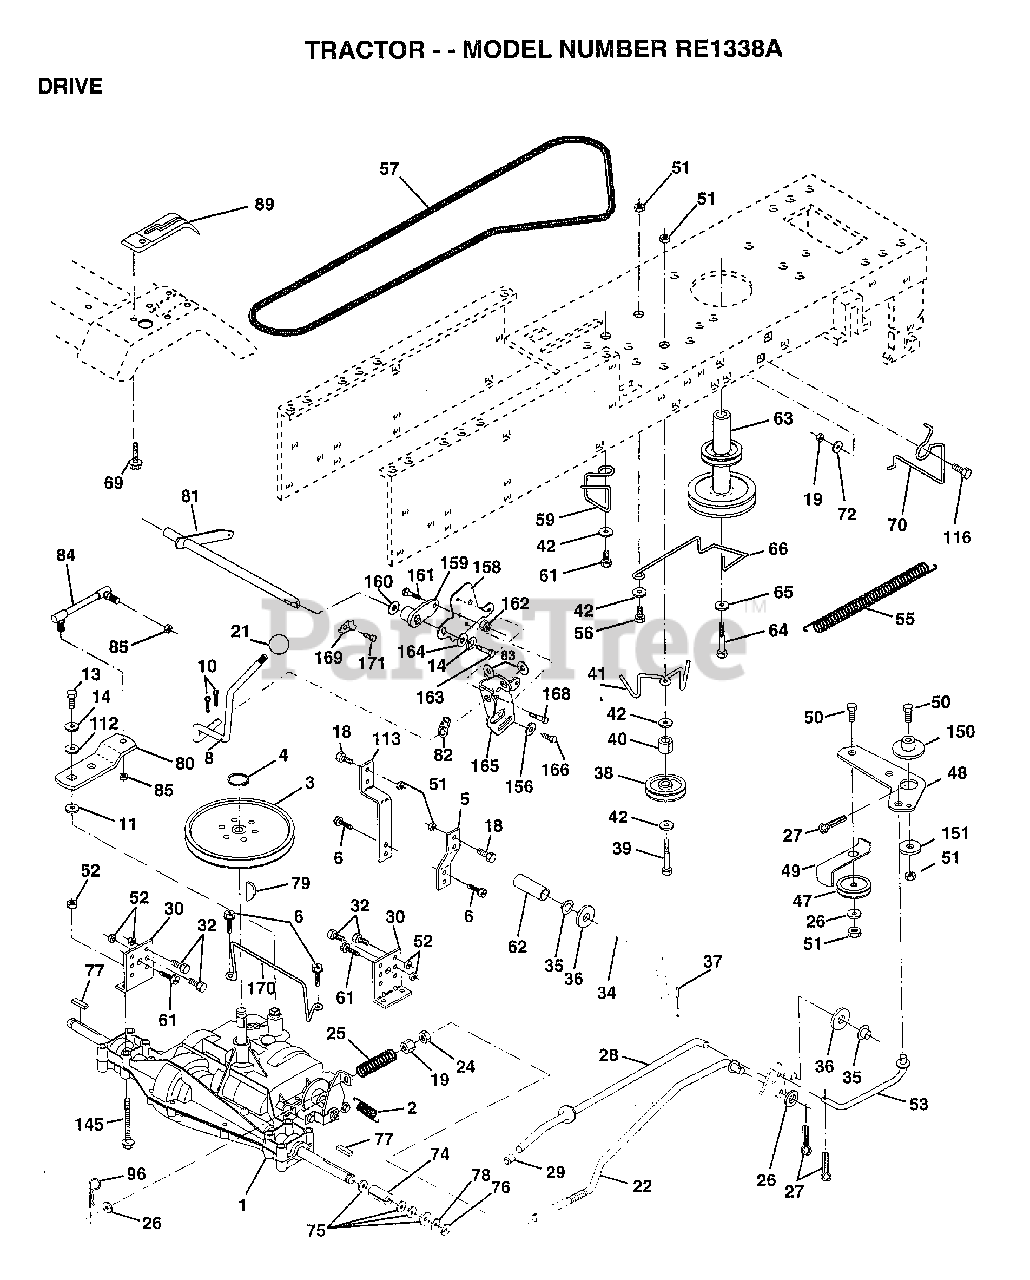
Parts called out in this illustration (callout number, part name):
2	SPRING.BRAKE.RETU
3	PULLEY TRANS
5	STRAP TORQUE
6	SCREW
8	ROD.SHIFT.FENDER.ADJ.LT.CRD
10	PIN COTTER 1/8
11	WASH-SHFT PLT LT
13	BOLT.1/4-28.W/PAT
14	LOCKWASHER
18	BOLT
19	NUT
21	KNOB T (1/2-HOLE)
22	BRAKE ROD
24	NUT
25	SPRING ROD LT
26	WASHER
27	COTTER PIN
28	ROD.BRAKE.PARK.LT
29	PLUNGER CAP T
30	TRANSAXLE MTG BKT
32	BOLT
34	SHAFT ASM-PEDAL F
35	NYLON BEARING
36	WASHER LT
38	FLAT IDLER PULLEY
39	BOLT
40	SPACER T
41	"KEEPER,BELT.IDLER FLAT"
42	WASHER
48	BELLCRANK.CLUTCH
49	RETAIN BELT
53	"LINK, CLUTCH T"
55	"SPRING, RETURN LT"
59	KEEPER BELT CNTSP
61	SCREW
62	PEDAL COVER T
63	PULLEY.ENGINE
64	BOLT
65	LOCKWASHER
66	KEEPER-BELT
70	KEEPER BELT ENG
72	WASHER
74	SPACER AXLE
75	WASHER
76	E-RING LT
77	SQUARE KEY
78	WASHER
80	"ROD,LINK SHIFT"
80	"SPRING,TORSION"
81	SHAFT.ASM.CROSS
83	WASHER
84	LINK.TRANSAXLE
85	NUT.CNT.LOCK.1/4
89	CONSOLE.SHIFT.LT.5SP.GREY
90	NUT
96	RETAINER M
112	WASHER LT
113	"STRAP,TORQUE"
116	BOLT RDHD 3/8-16
145	BOLT.HEX.FLGHD
150	BUSHING.BELLCRANK.GRD.DR
151	WASHER
156	WASHER.SRRTD.5/16
158	BRKT.SHIFT.MOUNT
159	HUB.SHIFT
160	WASHER
161	BOLT T
164	WASHER.5/8X.281X10GA
165	BRKT.PIVOT.LEVER
166	SCREW.5/16-18X5/8
168	BOLT.SHOULDER.5/16-18X.561
169	PLATE.FASTENING
170	KEEPER.BELT.TRANSAXLE
171	SCREW LT
